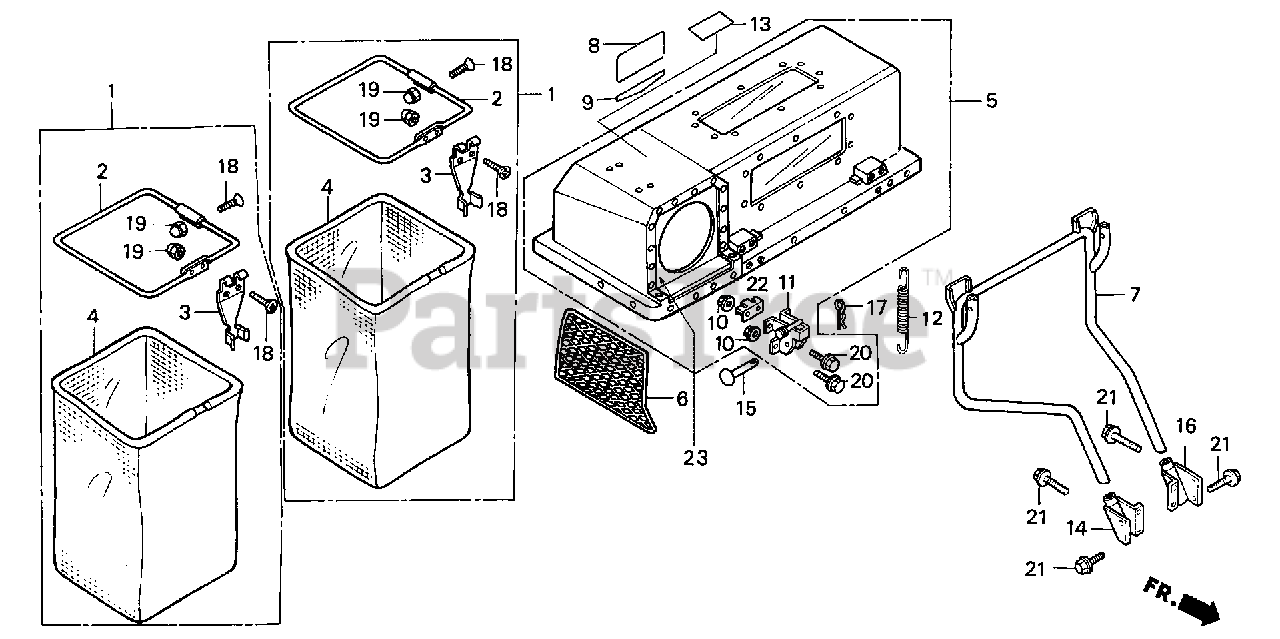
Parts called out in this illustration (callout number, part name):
1	BAG ASSY., GRASS
2	RIM, GRASS BAG
3	JOINT, GRASS BAG
4	FABRIC, GRASS BAG
5	HOPPER, TOP
7	POST, SUPPORTER
8	LABEL, HOPPER TOP
9	LABEL, OPEN
10	NUT, FLANGE (6MM)
12	SPRING, HINGE
13	LABEL B, HOPPER TOP
14	BRACKET, R. MOUNTING
15	PIN, HINGE
16	BRACKET, L. MOUNTING
17	PIN, LOCK (10MM)
18	SCREW, FLAT (6X16) (YAMADA)
19	NUT, CAP (6MM)
20	BOLT, FLANGE (6X18)
21	BOLT, FLANGE (8X16)
22	PATCH, HINGE
23	SEAL, HOPPER
